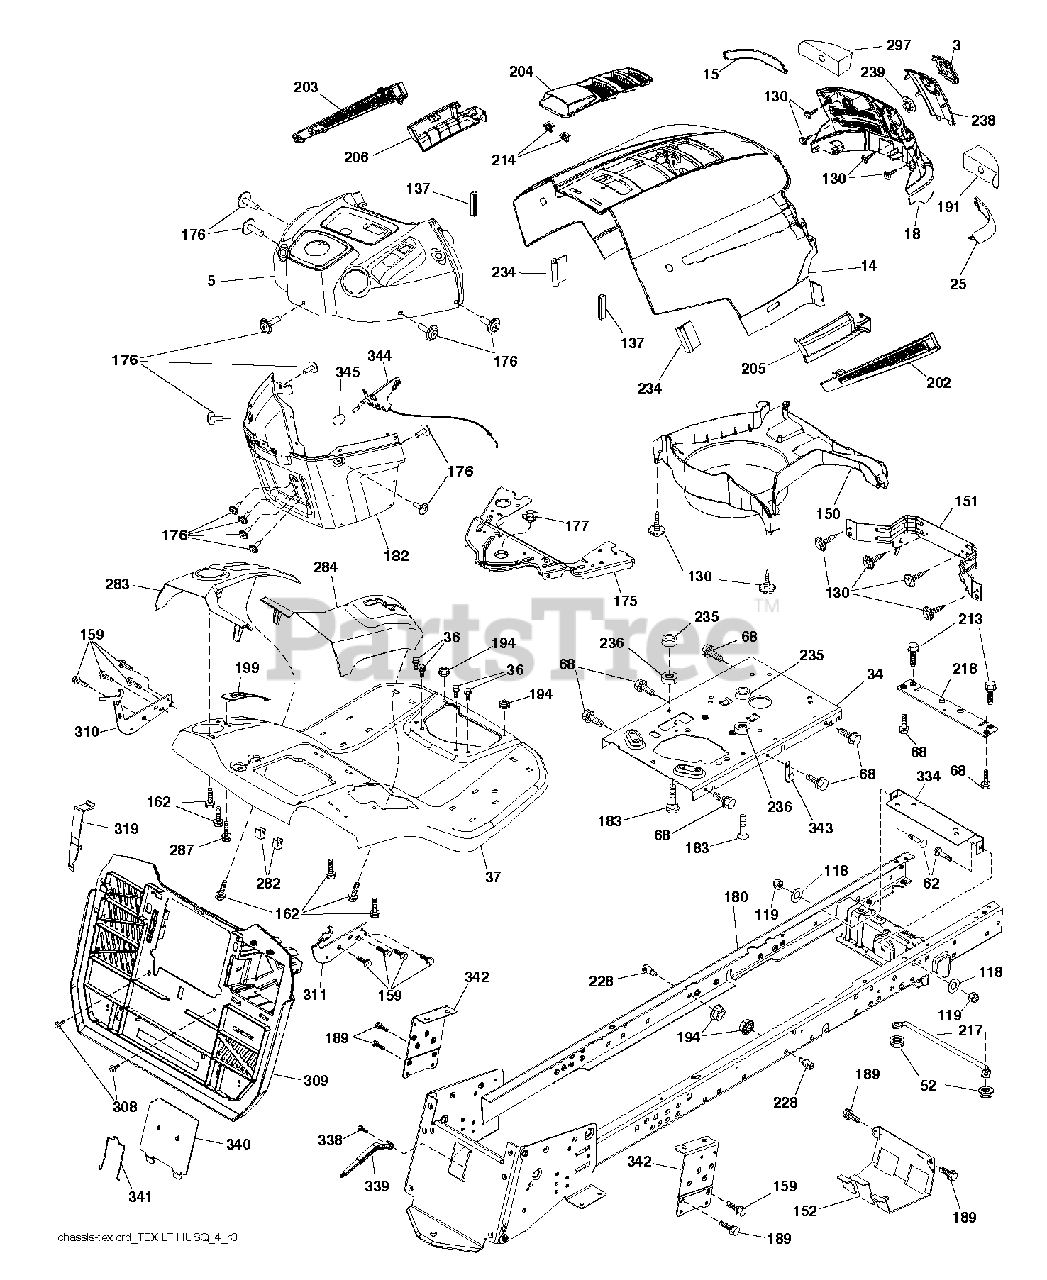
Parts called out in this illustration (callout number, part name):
3	LOGO.HUSQ.GT.LT.CROWN.H
5	SUBASM.DASH.UPPER.HLT.498
14	HOOD.HUSQVARNA.LT.ORANGE
15	LENS.HUSQVARNA LT.RH
18	GRILLE.SVC.HUSQVARNA.GREY
25	LENS.HUSQVARNA LT.RH
34	PLATE.ENGINE.10GA.CRD.GENII
36	SCREW 5/16"
37	FENDER.TEX.SRD.CRD.BASE
52	LOCKNUT
62	BOLT D
68	SCREW LT
118	WASHER
130	SCREW.#10 X 0.750.BOS
137	BUMPER DASH
151	BRACKET PIVOT
152	SHIELD.BROWNING.W/TEX
159	SCREW, 3/8-16X3/4
162	SCREW.HI-LO.CONSOLE
175	CROSSMEMBER
176	SCREW.#10-24X5/8.RN.QU
177	BUSHING STEERING
180	CHASSIS WLDT TEX CRD
182	DASH DASH. LOWER. PREDATOR. LT
183	BOLT.5/16-18X1-1/4 FULL THD
189	SCREW
191	INSERT.REFLECTIVE.RH.
194	NUT LOCK HEX FLANGE 5/16-18
199	PLATE DECK LIFT
202	VENT.SIDE.HUSQVARNA.LT.RT
203	VENT.SIDE.HUSQVARNA.LT.LFT
204	SUBASM.TOP.VENT.HUSQ.LT
205	SKIRT.SIDE.HUSQVARNA.LT.RT
206	SKIRT.SIDE.HUSQVARNA.LT.LEFT
213	BOLT
214	CLIP.RETAINER.TINNER.
217	ROD.PIVOT.HOOD
218	X-PIECE.HOOD.STOP.NON/
228	STUD.FASTNER.W/ANTI-ROTATE
234	BUMPER.HOOD.TEX.HUSQVARNA
235	SPACER FENDER
236	NUT.CENTERLOCK.5/16-
238	TRIM.HUSQ LT.668
282	CLIP.RETAINER.CONSOLE.LT.HUSQ
283	CONSL.DECKLIFT.LH.SRD.TEX.CRD
284	CONSL.SHFT.PEDAL.RH.SRD.TEXCRD
287	SCREW 1/4X20
297	INSERT REFLECTIVE
308	BOLT, 5/16-18 X 1 3/4
309	BACKPLATE.TEX.CRD
310	LH.ADJUST.HANGER.BRACKET.ASM
311	RH.ADJUST.HANGER.BRACKET.ASM
319	BRACKET.ACTUATOR.BAGGER.SRD
334	BRACKET.ENGINE
338	BOLT BOLT SHOULDER
339	LEVER LEVER BAGGER
340	DOOR.PNT.BATTERY.TRY.TEX.CRD.
341	LATCH
342	SUPPORT SUPPORT FENDER
343	CLIP CLIP
344	CONTROL.EZ.MULCH.TEX/CRD
345	RP KNOB.OVAL.TAPERED.3/8-16BLK
